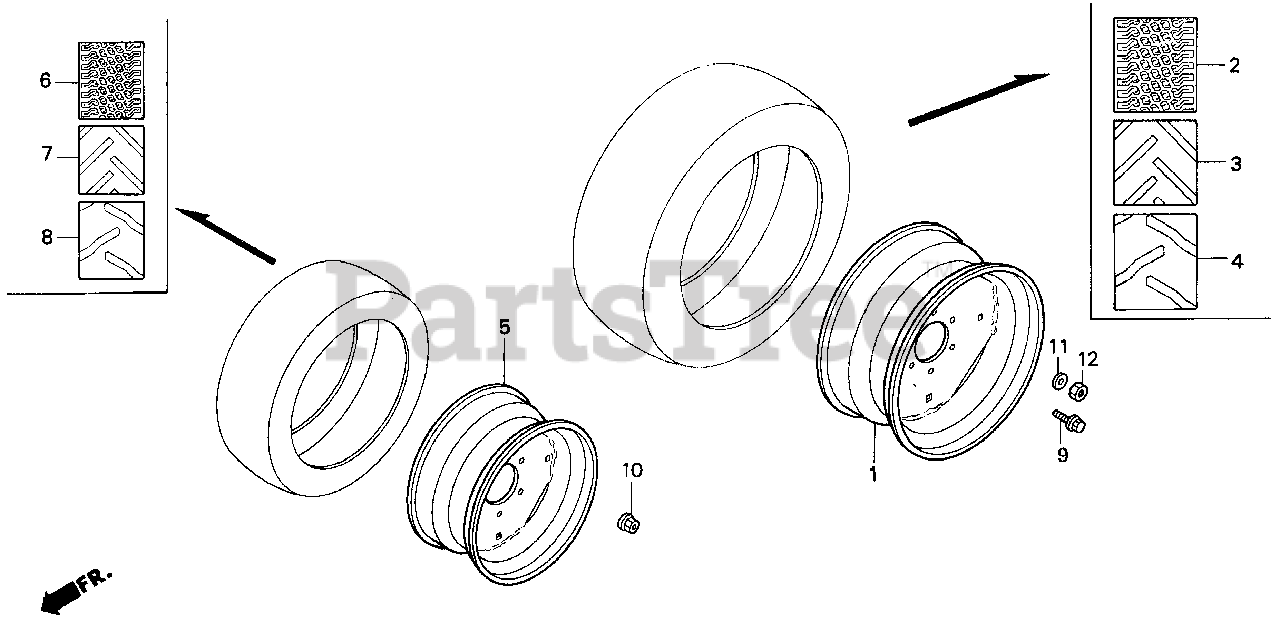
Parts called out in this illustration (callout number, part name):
1	WHEEL (15X10LB D.C.) (DICO)
1	WHEEL (16XW8L D.C. DICO)
2	TIRE (33X12.50-15) (TURF)
3	TIRE (12.5L-15 H.F.)
4	TIRE (9.5-16 AG.) (GOODYEAR)
5	WHEEL (12X7JA) (DICO)
5	WHEEL (12X5JA) (DICO)
6	TIRE (23X8.50-12) (TURF)
7	TIRE (23X8.50-12) (H.F.)
8	TIRE (6-12) (AG.) (GOODYEAR)
9	BOLT, HEX. (16X28)
10	NUT, WHEEL (12MM)
11	WASHER, PLAIN (16MM)
12	NUT, HEX. (16MM)
